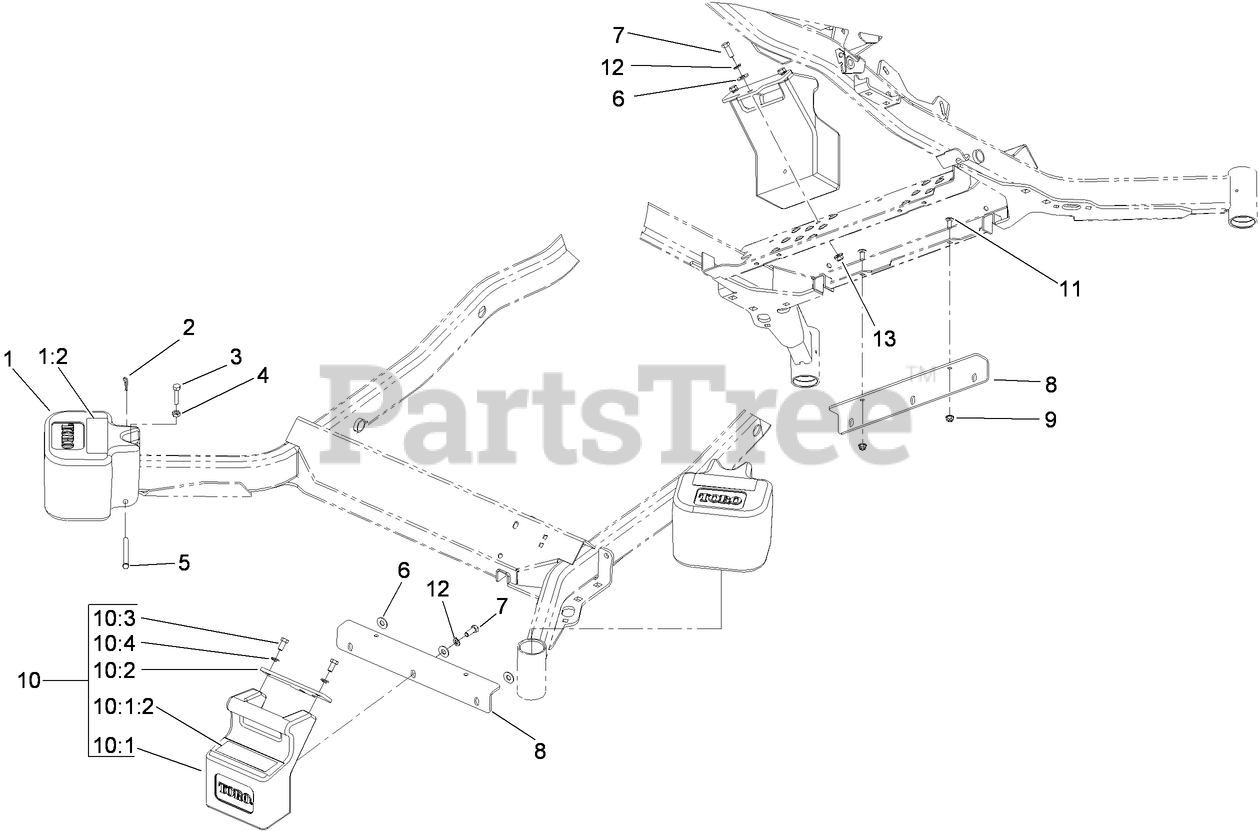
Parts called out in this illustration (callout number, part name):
1	63 LBS WEIGHT ASM
1:2	DECAL-WARNING
2	PIN-COTTER
3	BOLT-HH
4	NUT-HEX
5	PIN-CLEVIS
6	WASHER-FLAT
7	SCREW-HH
8	BRACKET-MOUNT, WEIGHT
9	NUT-HF, NI
10	WEIGHT ASM
10:1	OBS WEIGHT
10:1:2	Decal-Warning, Counterweight
10:2	TAB-SUPPORT, WEIGHT
10:3	SCREW-HH
10:4	WASHER-LOCK
11	SCREW-CARR
12	WASHER-LOCK
13	NUT-HF, NI
